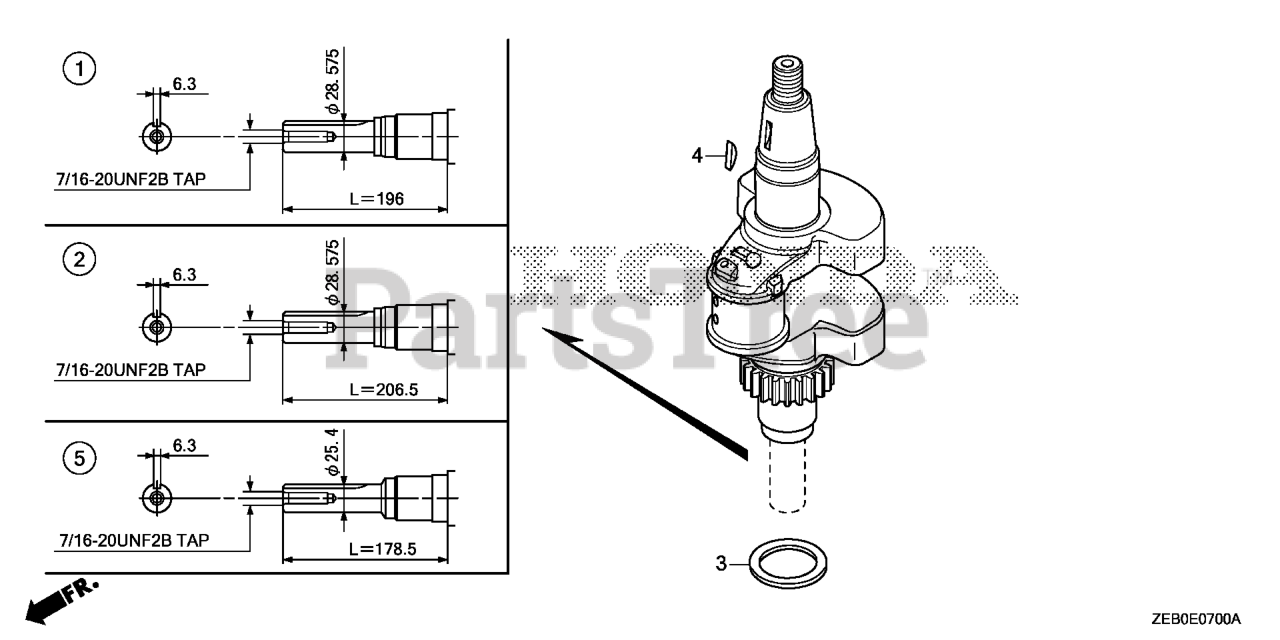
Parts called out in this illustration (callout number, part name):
1	CRANKSHAFT
3	WASHER, CRANKSHAFT THRUST
4	KEY, SPECIAL WOODRUFF (25X18)
